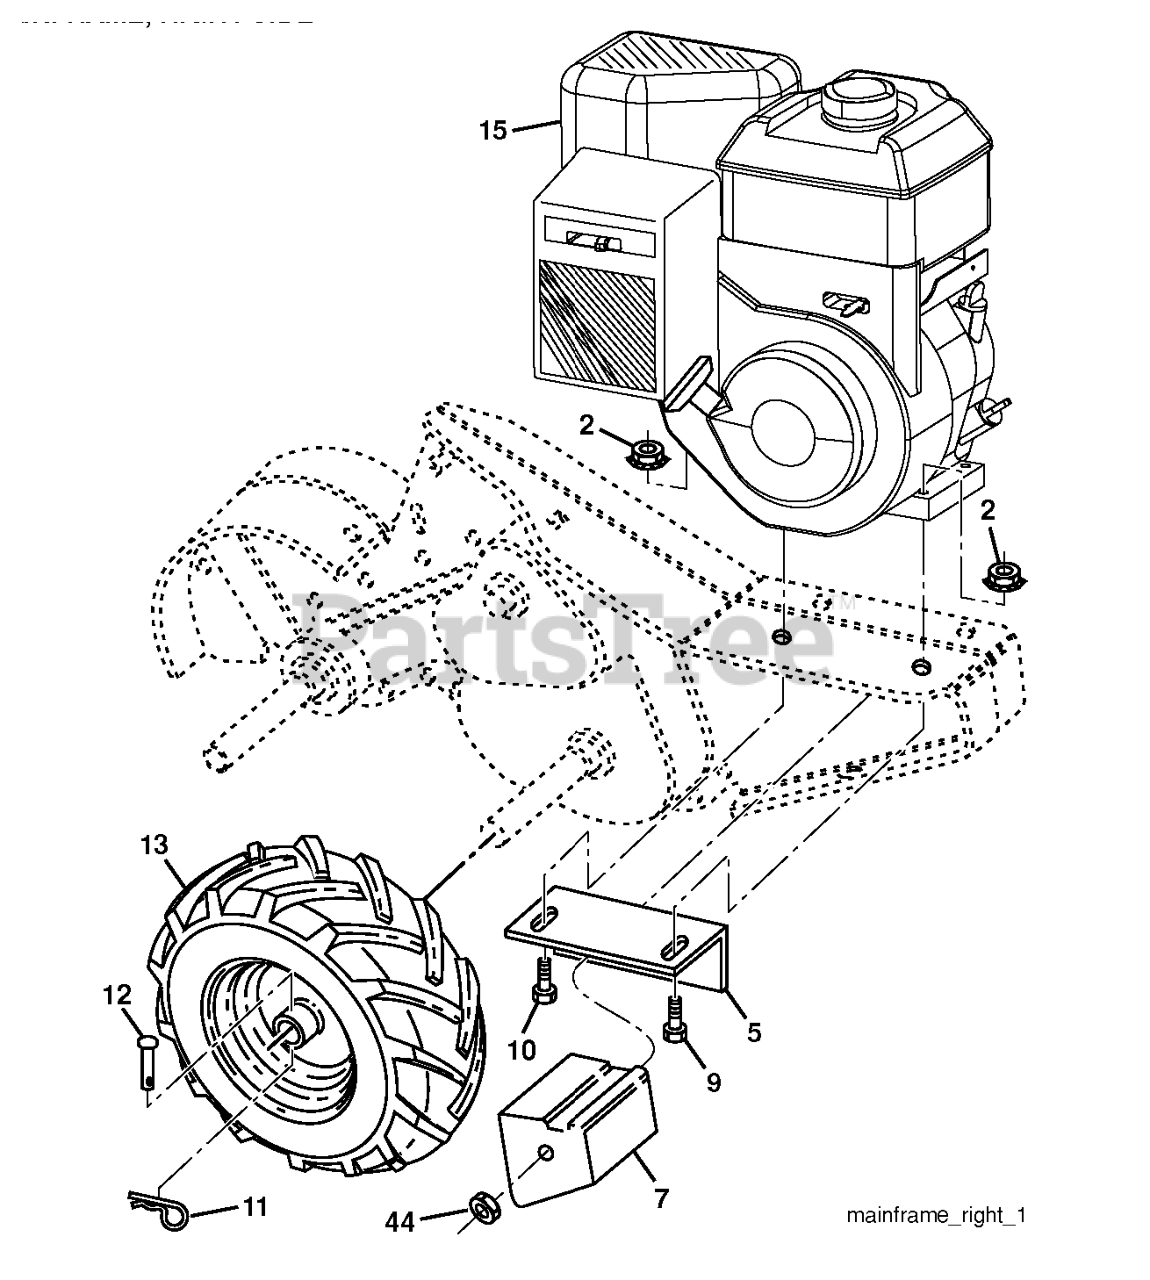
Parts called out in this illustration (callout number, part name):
2	LOCKNUT-FLANGE 5/16-18
5	BRACKET.REINFORCEMENT.RH.BLACK
7	COUNTERWEIGHT.RH
9	BOLT, HEX 5/16-18X1-3/4
10	BOLT
11	RETAINER M
12	RIVET,DRILLED
13	WHEEL.ASM.CRT.RH.13X5X6.SILVER
